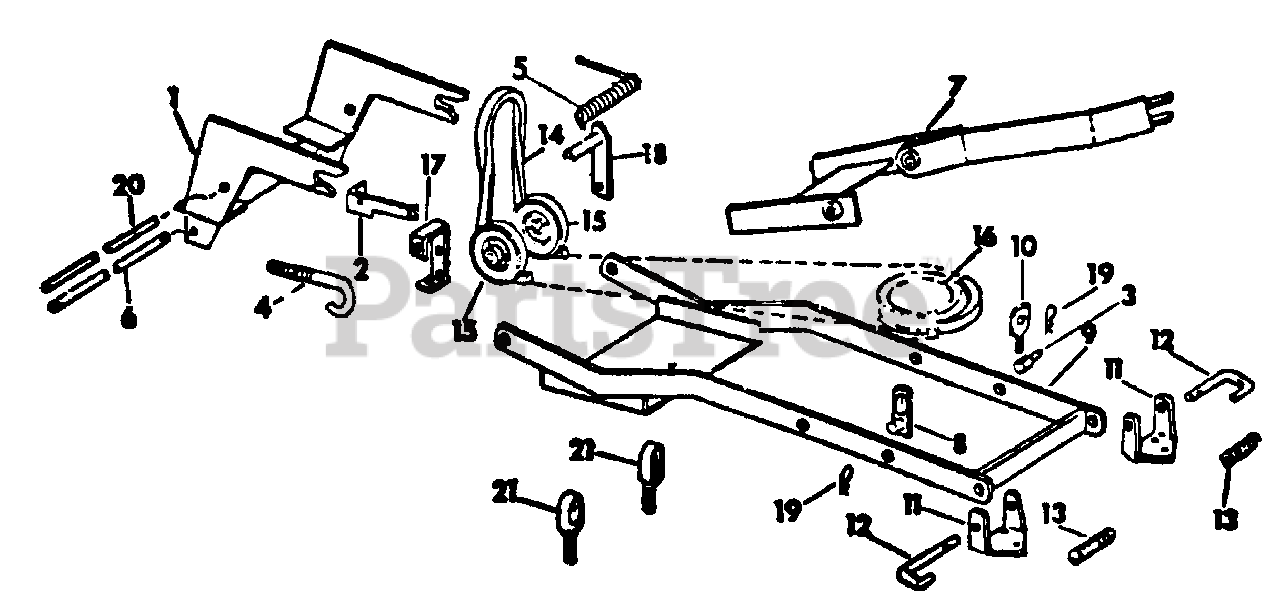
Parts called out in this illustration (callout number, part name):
1	Hanger Assy, Front
2	Ratchet, Idler
3	Block, Adjusting
4	Bolt, Idler Adjusting
5	Spring, Mule Drive Idler
6	Shaft, Frt Hanger
7	Frame Assy, Center
8	Link Assy, Lift
9	Frame Assy, Outer Lift
10	Link, Adjustable Lift
11	Bracket, Mower Support
12	Pin, Mower Support
13	Spring, Mower Support Pin
14	Belt, Mule Drive
15	Pulley, Drive Belt Idler
16	Pulley, Center
17	Arm, Idler LH
18	Arm Assy, RH Idler
19	Pin, Quick Attachable Cotter
20	Shaft, Idler Pivot
21	Hanger, Mower Support Front
